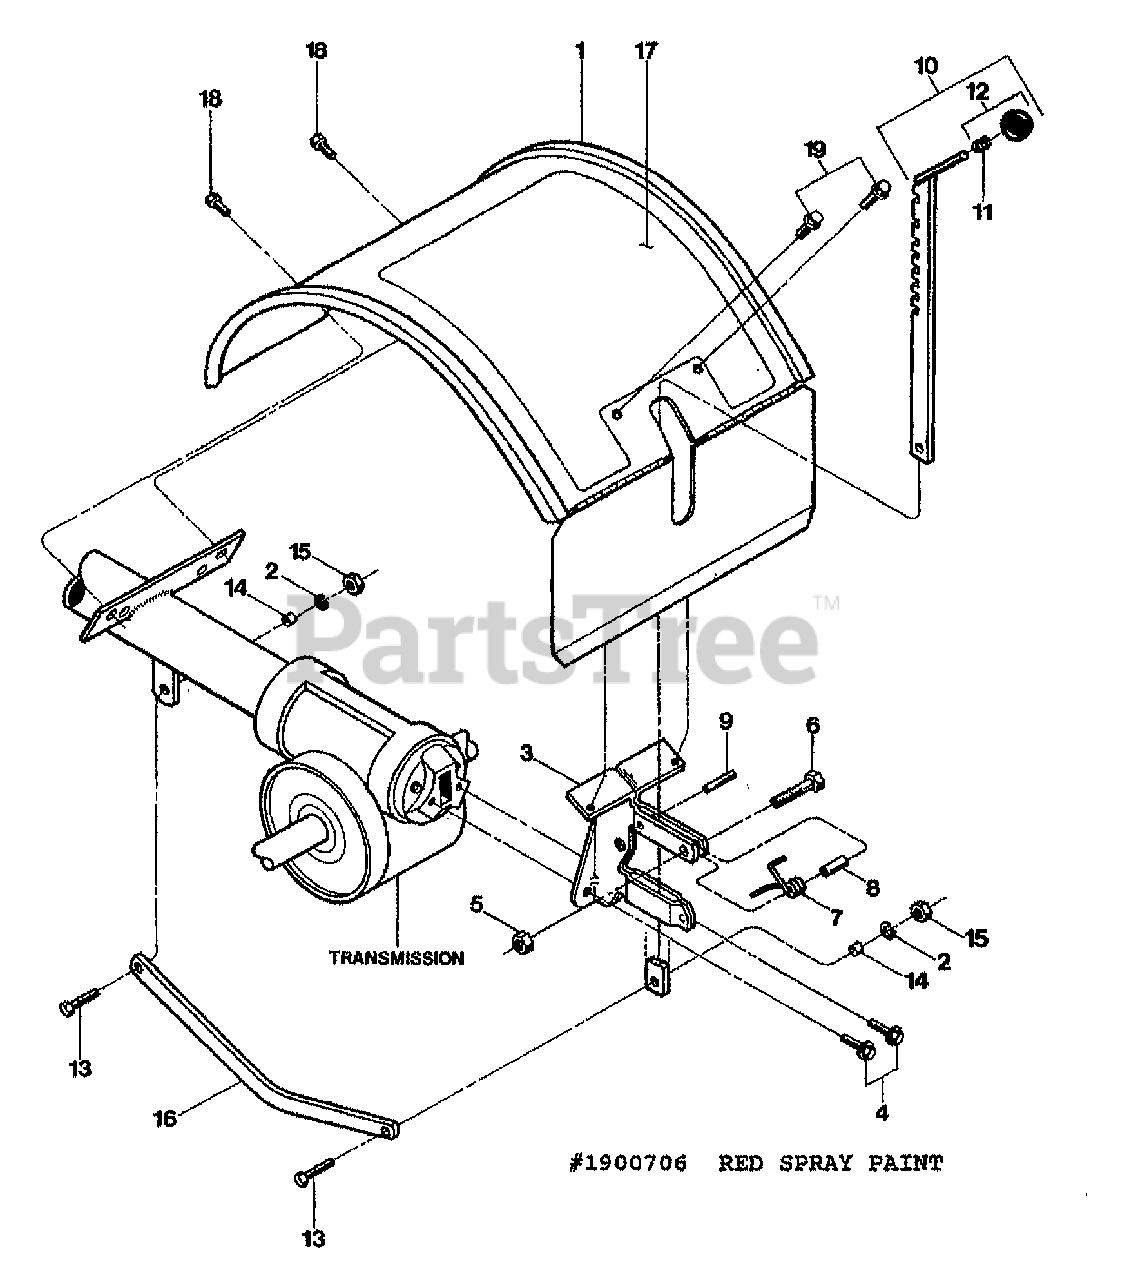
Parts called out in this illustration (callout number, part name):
1	HOOD W/DECALS PONY OPC (INCL. 17)
2	HOOD W/DECALS PONY (INCL 17) (15008,15009, 0400101 & HIGHER)
2	WASHER-LK .375 @ DEPL
3	BRKT W/ROLL PIN (9308)
4	SCR-HFLK 5/16-18X.62 G5ZP
5	NUT-LK 1/4-20
6	SCR-HH 1/4-20X1.0
7	SPRING-TORSION
8	SPACER-.250X.343X.375
9	PIN-ROLL .25 X 1
10	DEPTH REGULATOR W/KNOB (INCL. 11 & 12)
11	RING-TOLERANCE .5325 ID
12	KNOB-CONTROL (INCL. 11)
13	SCR-HH 3/8-16X1.25
14	BUSHING-.5X.375X.3
15	NUT-HEX 3/8-16 ZP
16	DRAG BAR-BENT
17	DECAL-HOOD OPER INST
17	DECAL-HOOD INST PONY (15008 & 15009 0400101 & HIGHER)
18	SCR-HWH 5/16-18 X .5 STH
19	SCR-HWH 1/4-20 X .5 STH (ATTACHES HOOD TO DEPTH REGULATOR BRACKET)
